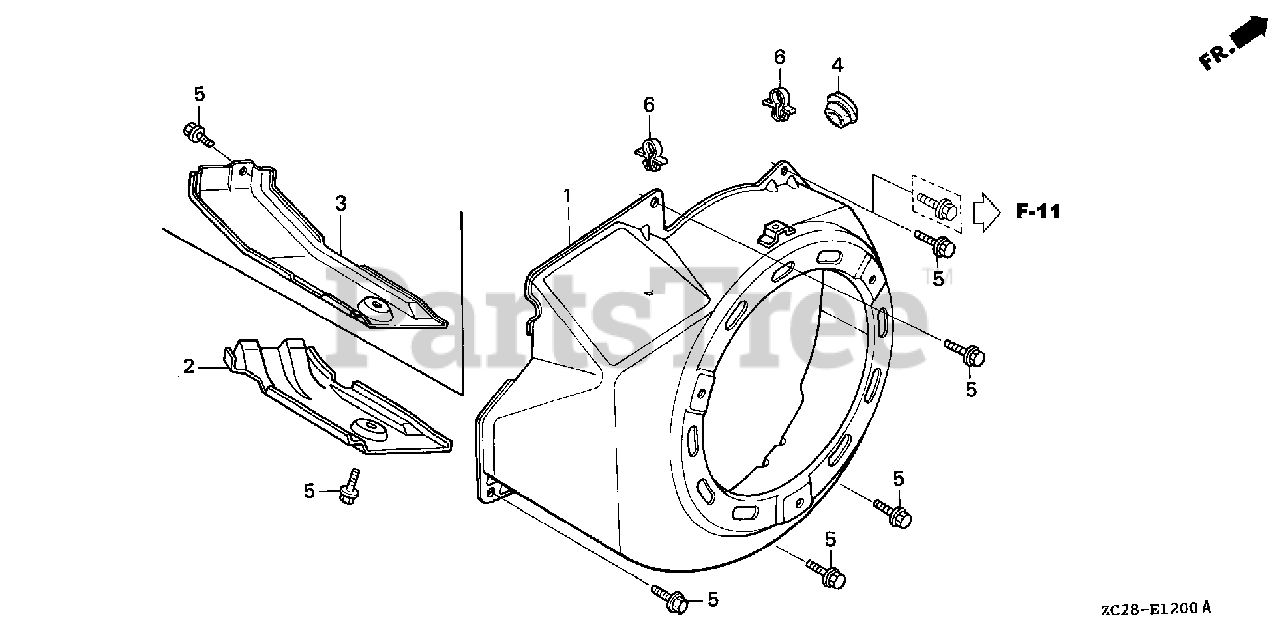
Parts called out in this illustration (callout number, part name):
1	COVER, FAN *NH1* (BLACK)
4	GROMMET, DRAIN HOLE
5	BOLT, FLANGE (6X12) (CT200)
6	CLIP, WIRE HARNESS (6MM) (WHITE)
